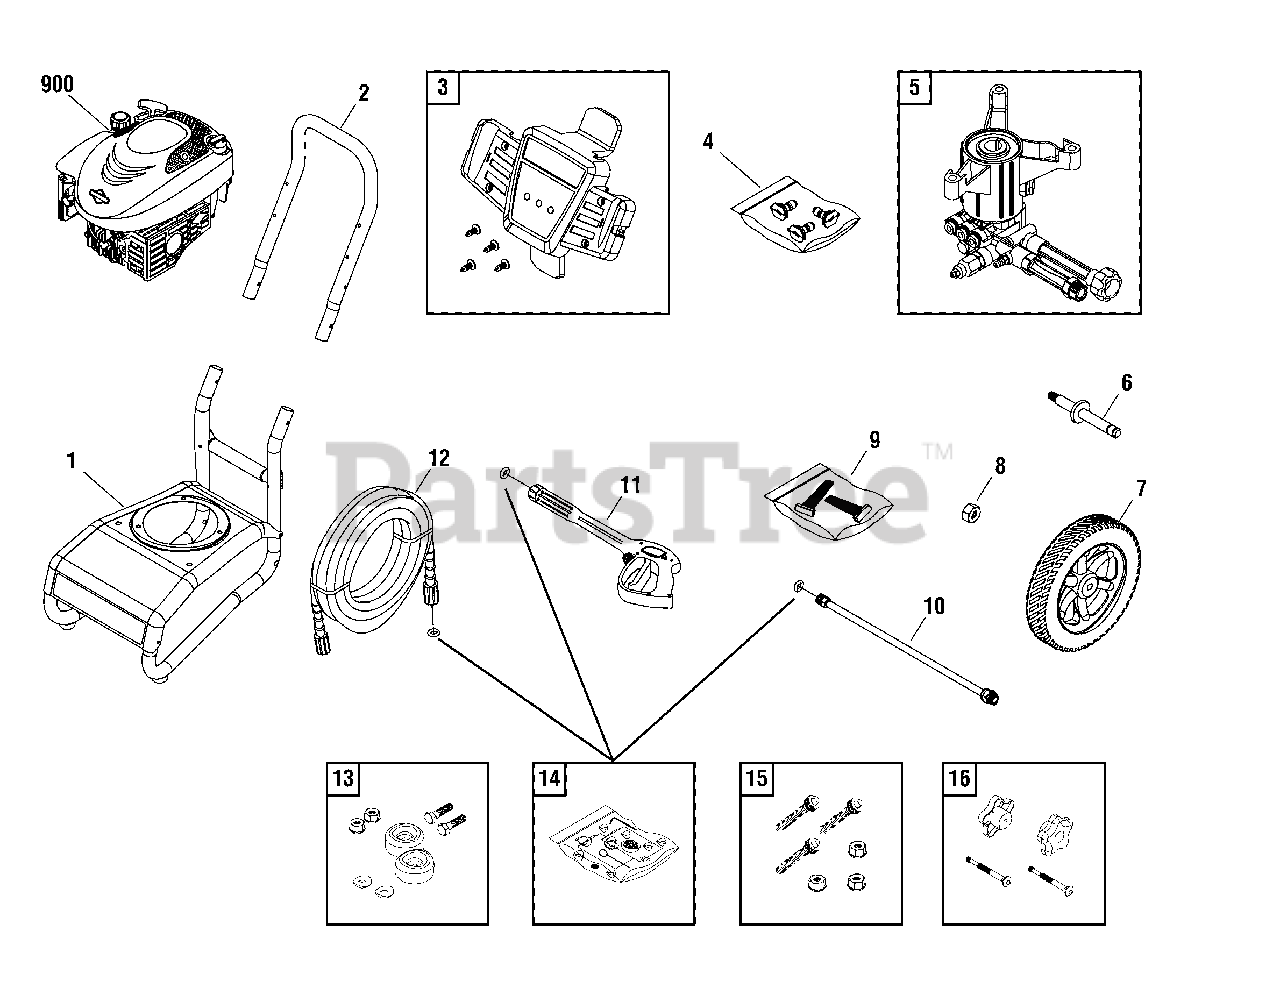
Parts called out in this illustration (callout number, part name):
1	BASE
5	PUMP
10	EXTENSION, QC
11	GUN
12	HOSE
13	MOUNT, Vibration
14	KIT, 0-RING
15	KIT, Hardware, Pump Mounting
